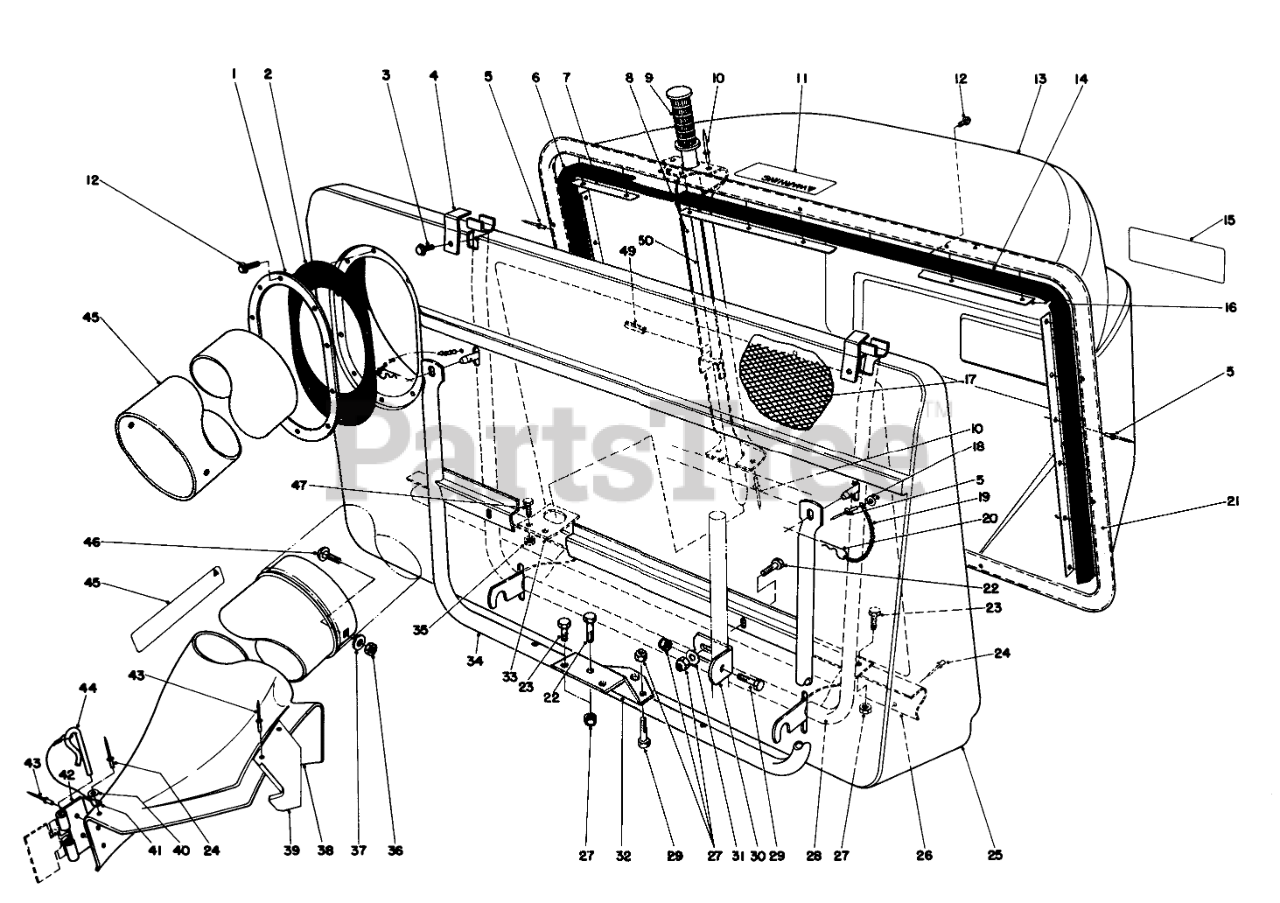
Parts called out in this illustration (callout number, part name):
1	RING-RETAINING
2	RING-RETAINER, RUBBER
3	SCREW-HWH
4	RETNR PIVOT BRKT
5	Rivet-Pop
6	RH BAG SEAL
7	RETNR TOP EXT.
8	DUMP HDLE CHANL WA
9	Grip Handle
10	Rivet
11	DECAL
12	SCREW-HWHTF
13	REAR GRASS BASKET
14	Seal-Bag LH.
15	EASY EMPTY BAG DECAL
16	BAG RETNR EXT.
17	Screen Bag
18	WASHER
19	10 LINK CHAIN W/O HOOK
20	PIN-HAIR
21	BAG SUPT ASM FRM
22	SCREW-HH
23	SCREW-HH
24	RIVET-BLIND
25	Bag Front
26	FRAME SUPT BRKT B
27	NUT-LOCK, CONE
28	Bag Frame
29	SCREW-HH
30	Bracket Mtg. Grass Catcher
31	WASHER-PLAIN
32	MTG PLATE B
33	Hanger-Frame Lower
34	BAG SUPPORT WA
36	NUT-KEPS
37	WASHER-FLAT
38	Chute Assembly (Incl. Ref. #24, 39-45)
39	CHUTE SUPT BRKT
40	Washer
41	LANYARD
42	BRACKET-MOUNTING, CHUTE
43	Rivet
44	PIN-LOCKING, CHUTE
45	Decal-Chute
46	BOLT-CARR
47	SCREW-HH
48	Duct
49	PIN-ROLL
50	DUMP HANDLE ASM
